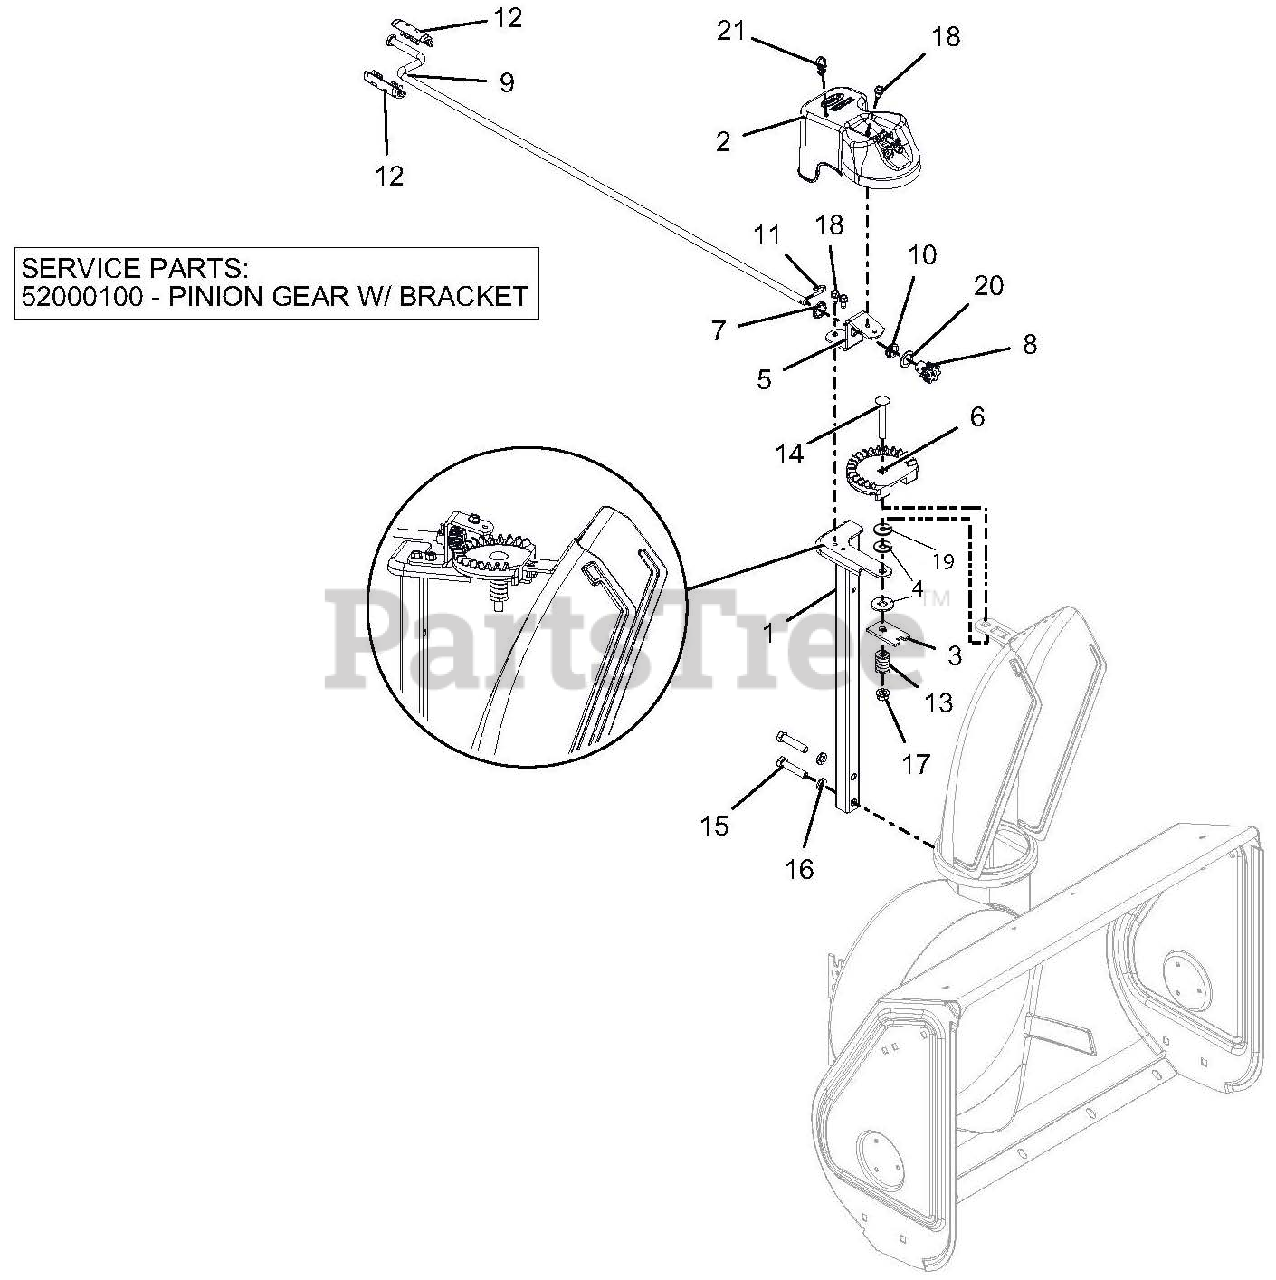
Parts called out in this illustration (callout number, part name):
1	CHUTE PEDESTAL, TALL COMPACT
2	GEAR COVER ASSY SM SHEAR BOLT
3	PLATE, FRICTION
4	FRICTION WASHER
5	BRACKET, PINION GEAR
6	CHUTE GEAR
7	PUSHNUT .625
8	PINION GEAR - CHUTE
9	ROD, CHUTE CRANK, COMP&SNOTEK
10	BUSHING, POLYLINER-.63 SNAPIN
11	PIN, SPRING CLIP
12	KNOB, CHUTE CRANK - SNAP GRAY
13	SG-COMP .187X.56X1.62
14	@BLT-RDHDSQNK .38-16X2.50 G5YZ
15	@BLT-HEX .38-16X1.75 GR5 YWZC
16	@WSHR-LK .38X.094 REG YWZC
17	@NUT-LK-TOP-FLG .38-16 YWZC
18	SCR-TAP .25-20X.50 HWH TR YWZ
19	@WSHR-FL-STL .406X1.25X.10 ZC
20	WSHR-THRST .625 X 1.0 X .03
21	CLIP, CABLE GUIDE
22	PINION GEAR W/BRACKET
